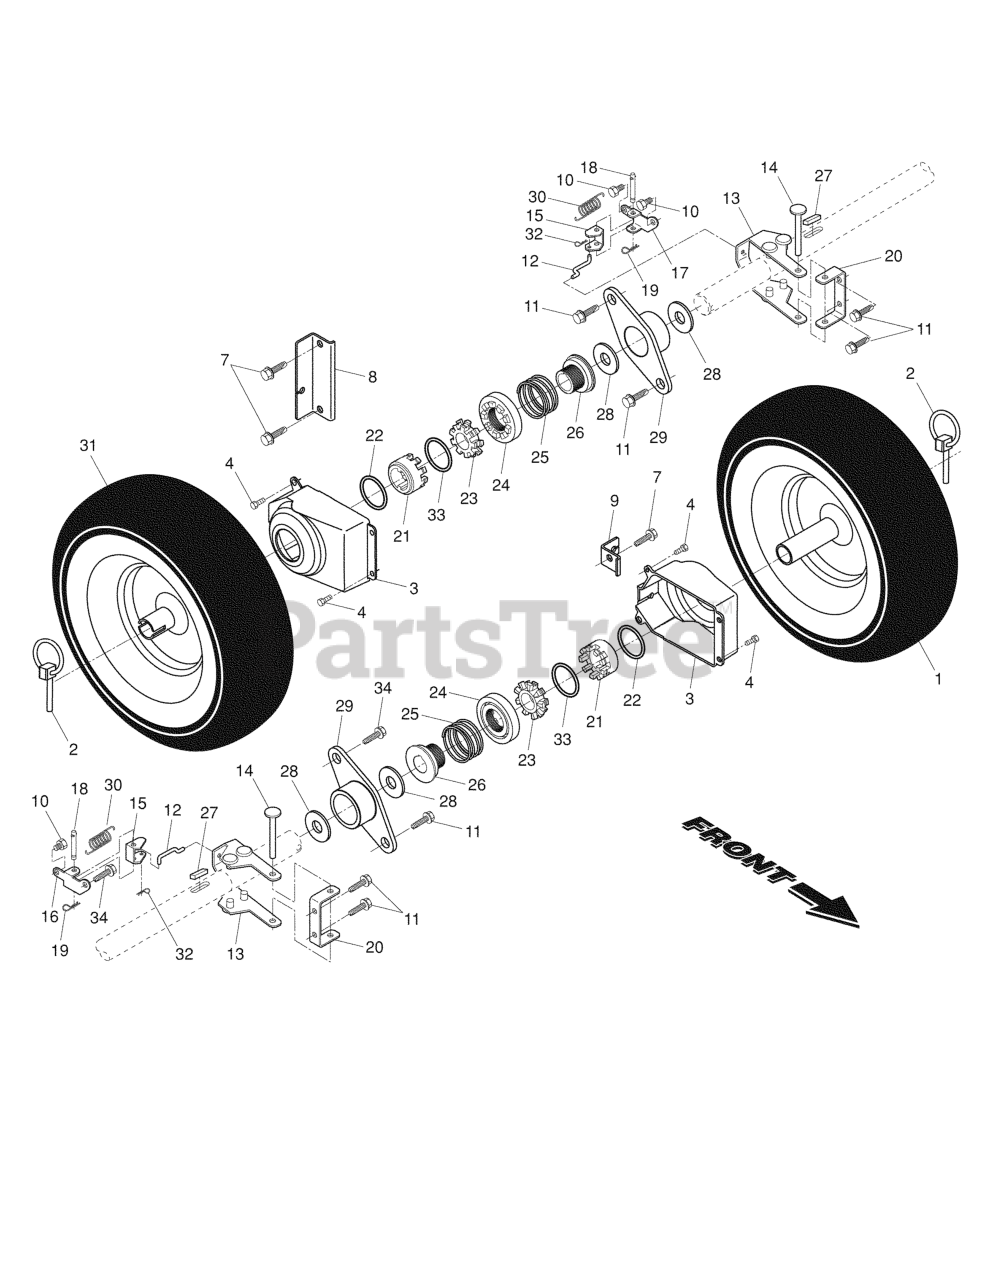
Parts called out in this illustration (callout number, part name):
1	16 X 4.8 LH WHEEL GREY
2	PIN KLIK, 1/4
3	COVER, POWER STEERING
4	SCREW, HEX HEAD, TAPPING
7	Capscrew, Hex Head, Flanged 3/8-16 x 1
8	BRACKET, STEERING CABLE RH
9	BRACKET, STEERING CABLE LH
10	SCREW 1/4X20
11	Screw, Hex Head 5/16-18 x 1/2
12	LINK.STEER.YOKE
13	YOKE, STEERING
14	PIN, STEERING LEVER
15	BELLCRANK.STEER
16	BRACKET.STEER.PIVOT.LH.YZ
17	BRKT.STEER.PIVOT.RH
18	PIN, STEERING BELLCRANK
19	RETAINER CLIP PM
20	BRACKET.STEER.PNT.BLACK
21	RP.DRIVER WHEEL
22	RING, WIRE RETAINER
23	LOBE WHEEL
24	RP.SLIDE.CLUTCH
25	SPRING, CLUTCH SLIDE
26	RP.LOBE.AXLE
27	KEY, SQUARE 1/4 X .875
28	WASHER TRUST 1"
29	BEARING, AXLE
30	SPRING LATCH
31	16 X 4.8 RH WHEEL
32	RETAINER CLIP
